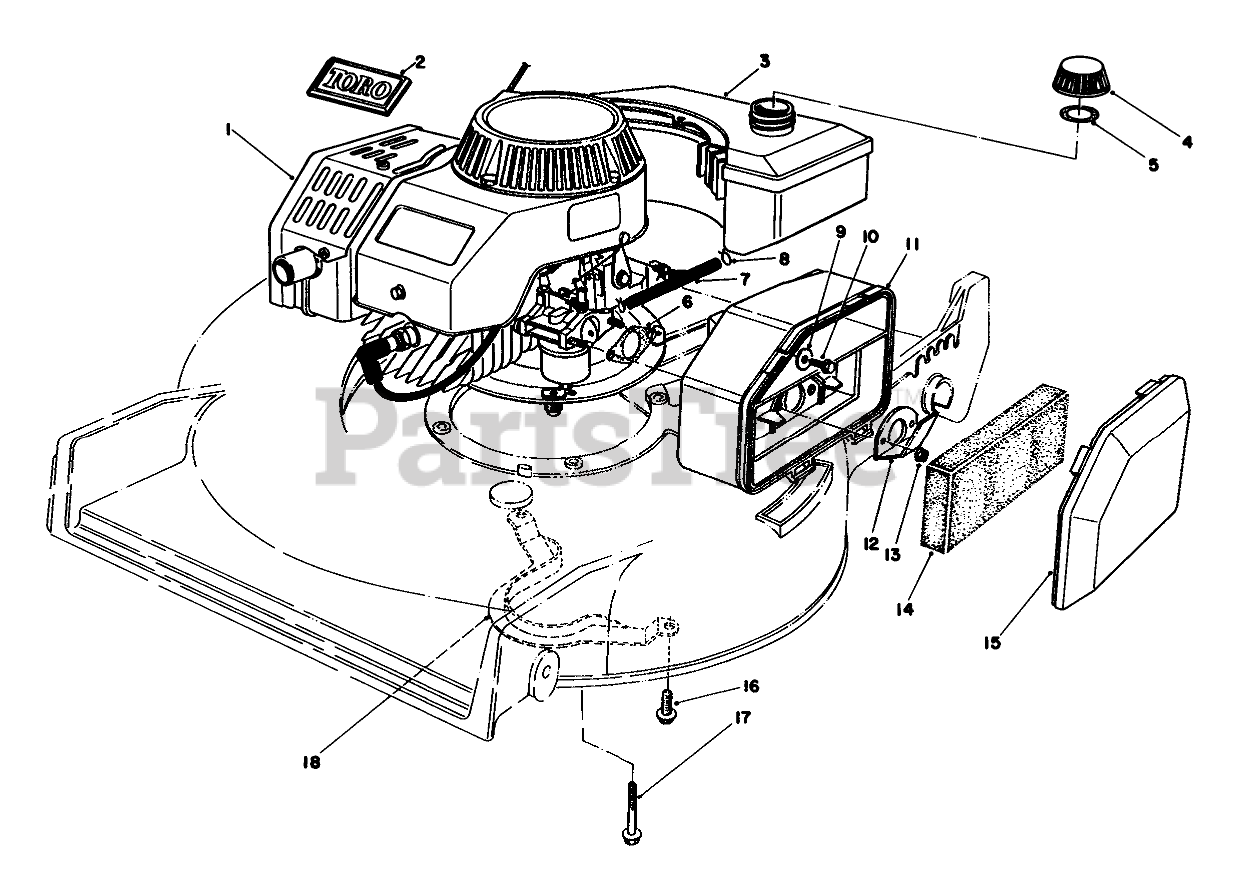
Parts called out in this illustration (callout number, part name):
1	Engine
2	TORO LOGO PLT
3	Gas Tank Assembly
4	Gas Cap Assembly (Incl. Ref. #5)
5	GAS CAP GASKET
6	GASKET-AIR CLEANER
7	FUEL LINE
8	CLAMP-HOSE
9	WASHER-FLAT
10	SCREW-HH
11	AIR CLEANER
12	SPIT BACK DEFLECTOR
13	NUT-LOCK
14	FILTER
15	AIR CLEANER COVER
16	Screw
17	SCREW-HHF
18	BELT GUIDE
